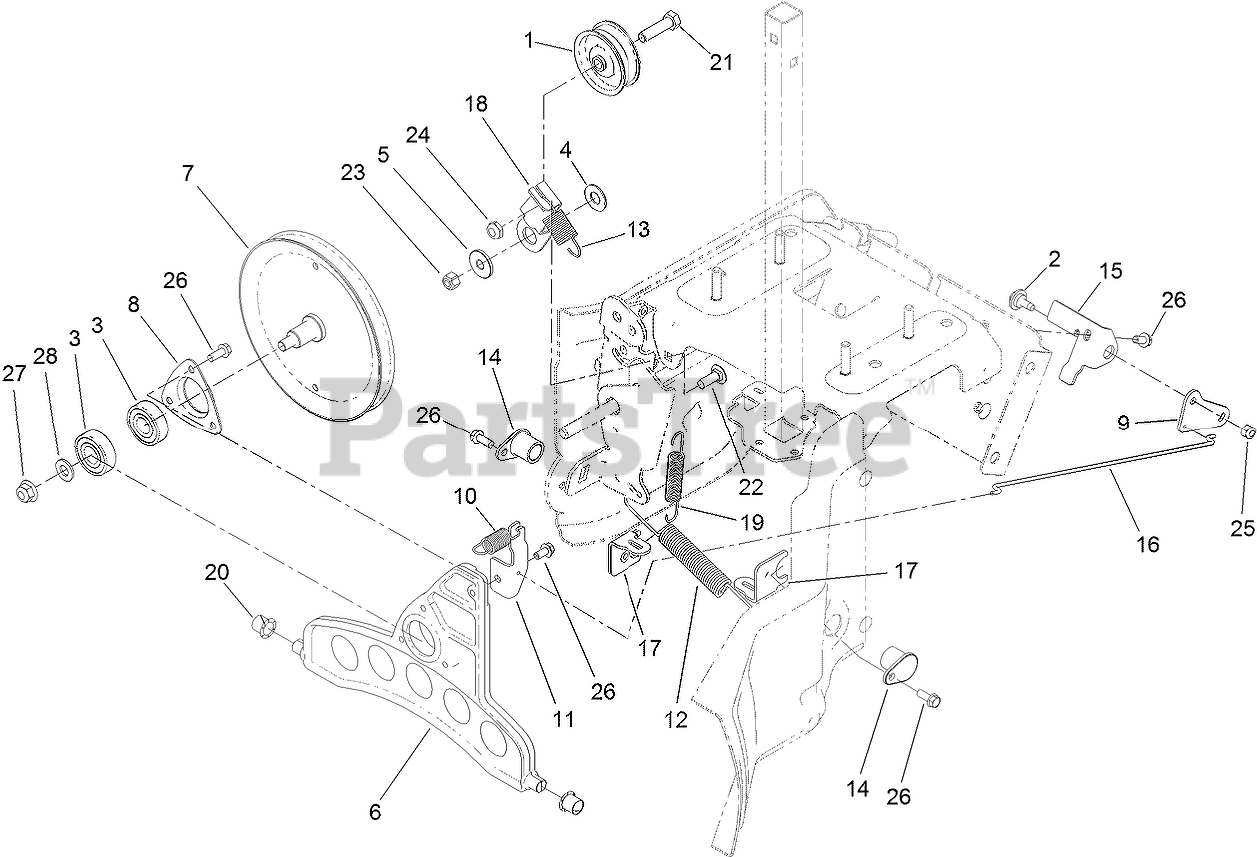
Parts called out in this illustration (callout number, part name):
1	PULLEY-IDLER
2	SCREW-SHOULDER
3	BEARING-BALL
4	WASHER
5	BUSHING-IDLER
6	PLATE-WHEEL, FRICTION
7	TRACTION PULLEY ASM
8	RETAINER-BEARING
9	BELLCRANK-DRIVE
10	SPRING-EXTENSION
11	BRACKET-PLATE, TRACTION
12	SPRING-EXTENSION
13	SPRING-EXTENSION
14	BUSHING-PLATE, TRACTION
15	BRACKET-BELLCRANK
16	LINK-DRIVE
17	BRACKET-ANCHOR, SPRING
18	ARM-IDLER, TRACTION
19	SPRING-EXTENSION
20	BUSHING-NYLINER
21	SCREW-HH
22	BOLT-CARR
23	NUT-HEX
24	NUT-HEX
25	NUT-HEX
26	SCREW-HWH
27	NUT-HF, NI
28	WASHER-FLAT
